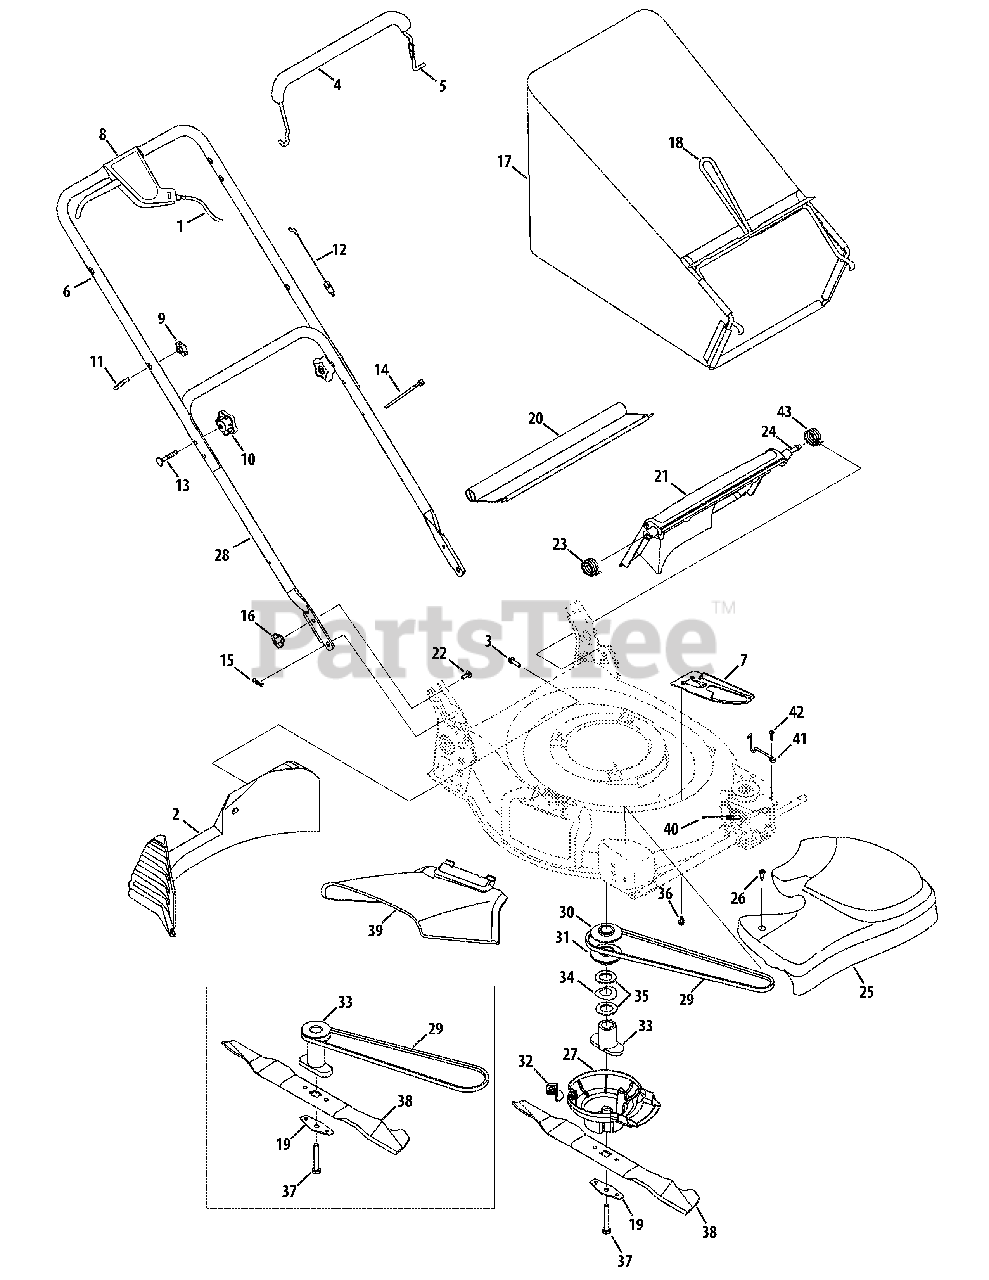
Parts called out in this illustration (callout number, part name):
1	Variable Speed Cable
2	Rear Baffle 22'' Rd.
3	Screw, 1/4-15 x 1.000
4	Deluxe Bail Cover - Yellow
4	Deluxe Bail Cover - Gray
8	Control Lever Assembly
9	Handle Knob
10	Star Knob
11	Eye Bolt
12	Control Cable - 40''
13	Carriage Bolt, 5/16-18 x 2.0
14	Cable Tie
15	Cotter Pin
16	Wing Nut
17	Grassbag Assembly - Yardman
17	Brassbag Assembly - Black
19	Blade Bell Support
20	Rear Trailing Shield
21	Rear Discharge Door
22	Carriage Bolt, 1/4-20
23	Torsion Spring - RH
24	Pivot Rod
25	Transmission Cover - Yellow
25	Transmission Cover - Gray
26	Shoulder Screw, #12-24
27	Engine Baffle
29	V-Belt
30	Upper Pulley Half, 25mm x 2.62
31	Lower Pulley Half, 25.mm x 2.62
32	Baffle Bracket
33	Blade Adapter, 25mm
34	Spacer Washer
35	Flat Washer
36	Screw, 1/4-14 x .625
37	Hex Screw, 3/8-24 x 2.50
38	21'' Muliching Blade
39	Side Discharge Chute
40	Extension Spring
41	Belt Keeper Wire
42	Torx Screw
43	Torsion Spring - LH
